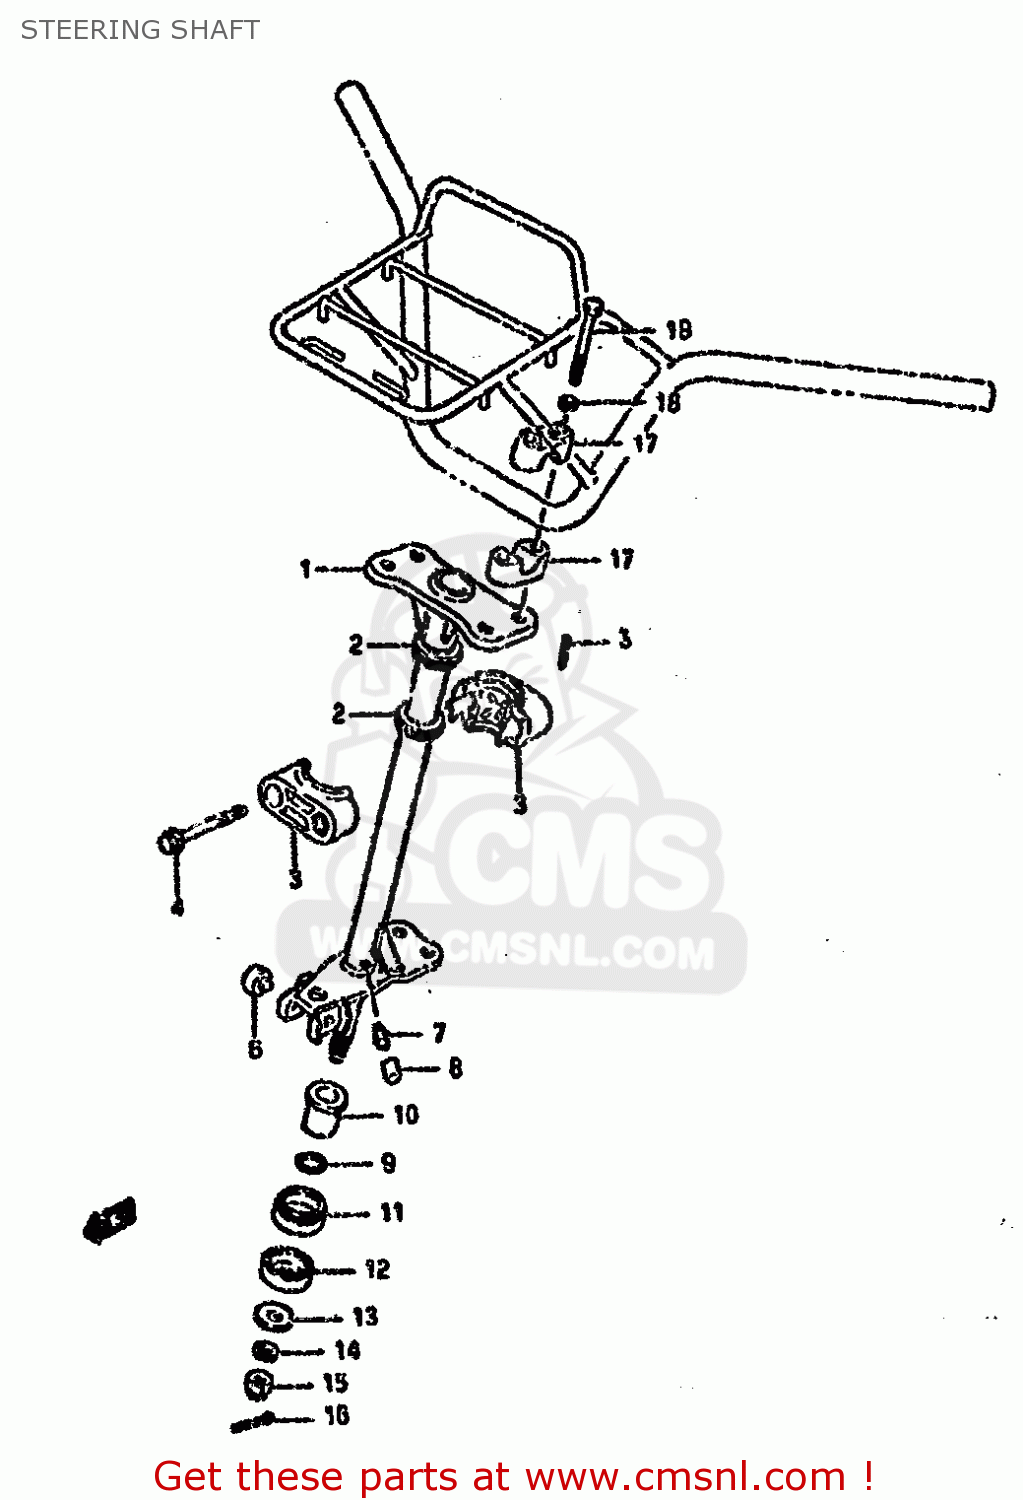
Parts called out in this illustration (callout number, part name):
1	SHAFT,STEERING
2	SEAL,STEERING SHAFT HLDR DUST
3	HOLDER,STEERING SHAFT
4	BOLT(8X80)
5	PIN 20X20
6	CUSHION
7	GREASE NIPPLE
8	CAP,GREASE NIPPLE
9	O RING(D:3.1,ID:16.8)
10	BUSH
11	DUST SEAL,STEERING SHAFT
12	SEAL,STEERING DUST,LOWER
13	WASHER (12.5X32X4.5)
14	WASHER
15	NUT
16	PIN 20X20
17	HOLDER,HANDLE UPR
18	WASHER,LOCK,8.
19	BOLT
